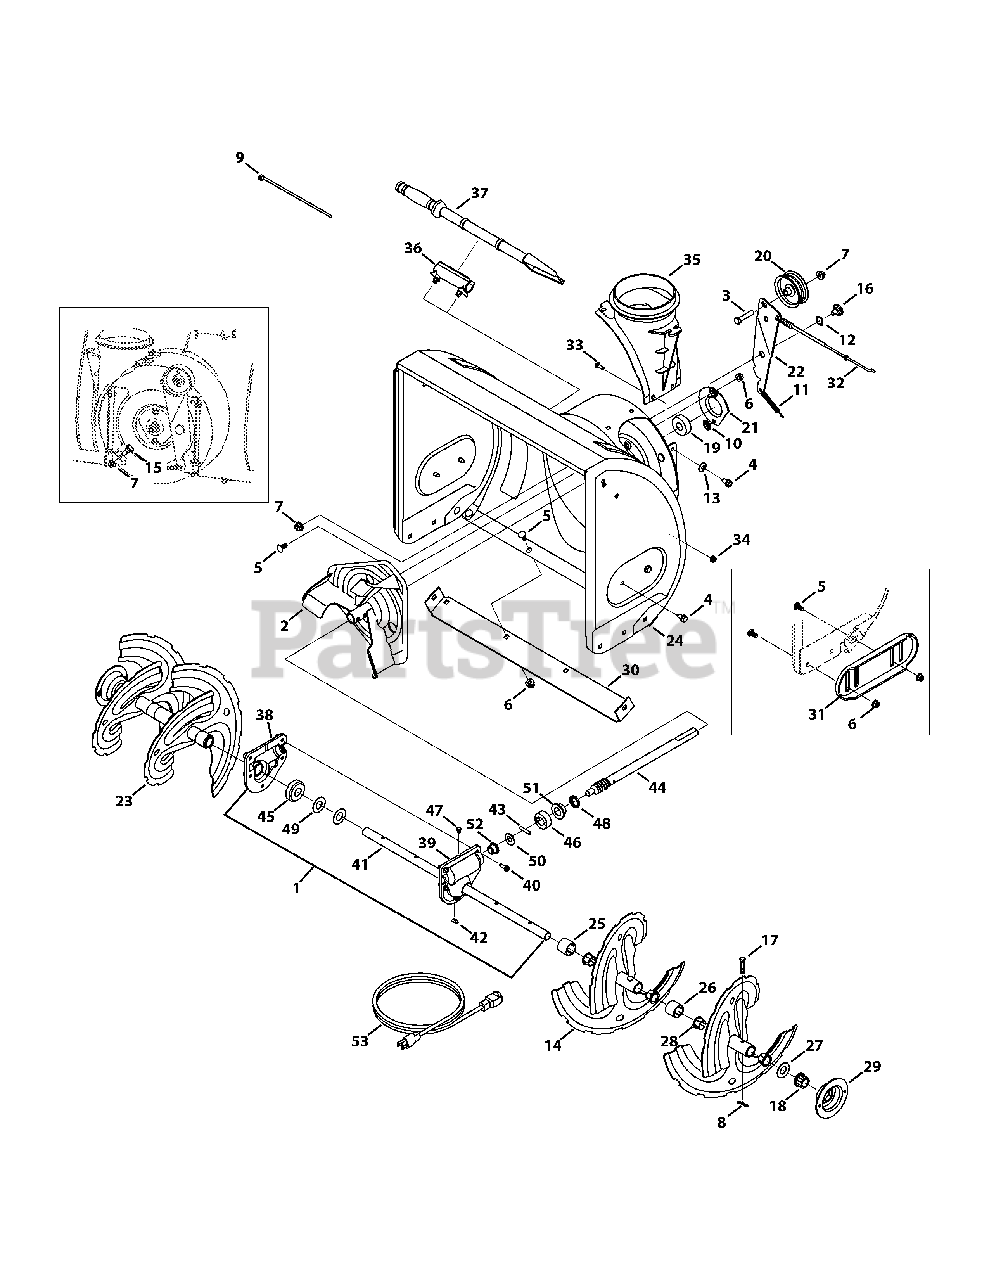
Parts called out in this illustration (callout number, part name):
1	Auger Gearbox 30", includes 38-52
2	Impeller Assembly, 12" Dia.
3	Hex Head Screw, 3/8-16 x 1.75
4	Screw, 5/16-18 x .750
5	Bolt, Carriage, 5/16-18 x .750
6	Nut, Flange lock, 5/16-18
7	Nut, Flange lock, 3/8-16
8	Bow-Tie Cotter Pin
9	Cable Tie, 7"
10	Nut, Push-on, .25 Dia.
11	Extension Spring, .38 x 4.59
12	Washer, Wave, .625 x .885
13	Washer, Bell, .340 x .872
14	Spiral Assembly, LH
15	Bolt, Shoulder, .496 x .336 x 3/8-16
16	Screw, Shoulder, .625 x .17 x 3/8-16
17	Shear Pin, .25 x 1.50
18	Bearing, Hex Flange, .75
19	Bearing, Ball, .75 x 1.85
20	Pulley, Idler, Flat, 2.75
21	Bearing, 1.85 ID
22	Auger Idler Bracket
23	Spiral Assembly, RH
24	Auger Housing Assembly
25	Spacer, 1.25 x .75 x 1.00
26	Spacer, 1.25 x .75 x 2.00
27	Washer, Flat, .76 x 1.49
28	Bushing, Flange, .800 x .910
29	Bearing, 1" Hex
30	Shave Plate, 2.25 x 29.66
31	Deluxe Slide Shoe
32	Auger Drive Clutch Cable
33	Screw, Carriage, 1/4-20 x .75
34	Nut, Flange lock, 1/4-20
35	Chute Adapter
36	Clean-Out Tool Mount
37	Clean-Out Tool
38	Reducer, RH
39	Reducer, LH
40	Screw, 1/4-20 x 0.750
41	Auger Axle, 30"
42	Key, Hi-Pro, 3/16 x 5/8
43	Dowel Pin, .25 x 1.25
44	Worm Shaft, .75
45	Gear Worm, 20T
46	Collar Thrust, .756 x .600
47	Plug, 1/4 x .437
48	Oil Seal, .75 x 1.131 x .188
49	Washer, Flat, .760 x 1.50
50	Washer, Flat, .51 x 1.12
51	Bearing, Flange, .75 x 1.00 x .59
52	Bearing, Flange, .50 x .75 x .59
53	Extension Cord, 110V
